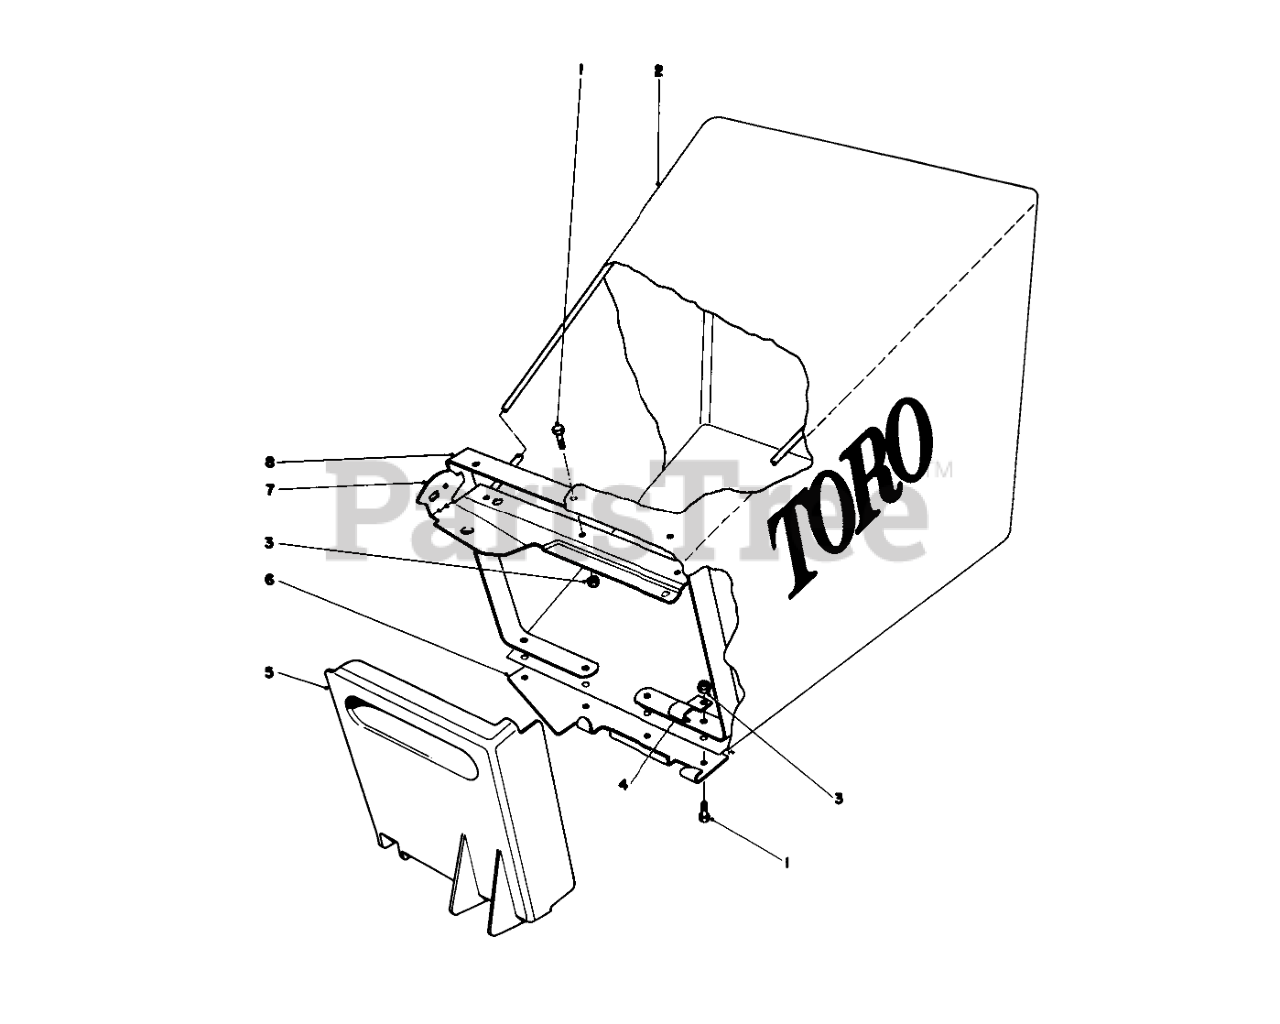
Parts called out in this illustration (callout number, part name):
1	216 Washer
2	REPLACMNT BAG 44-0530
3	Locknut
4	SUPPORT BRACKET
5	BAG DOOR
6	DOOR BRACKET
7	BAG FRAME WA
8	1 10 Bag Support
